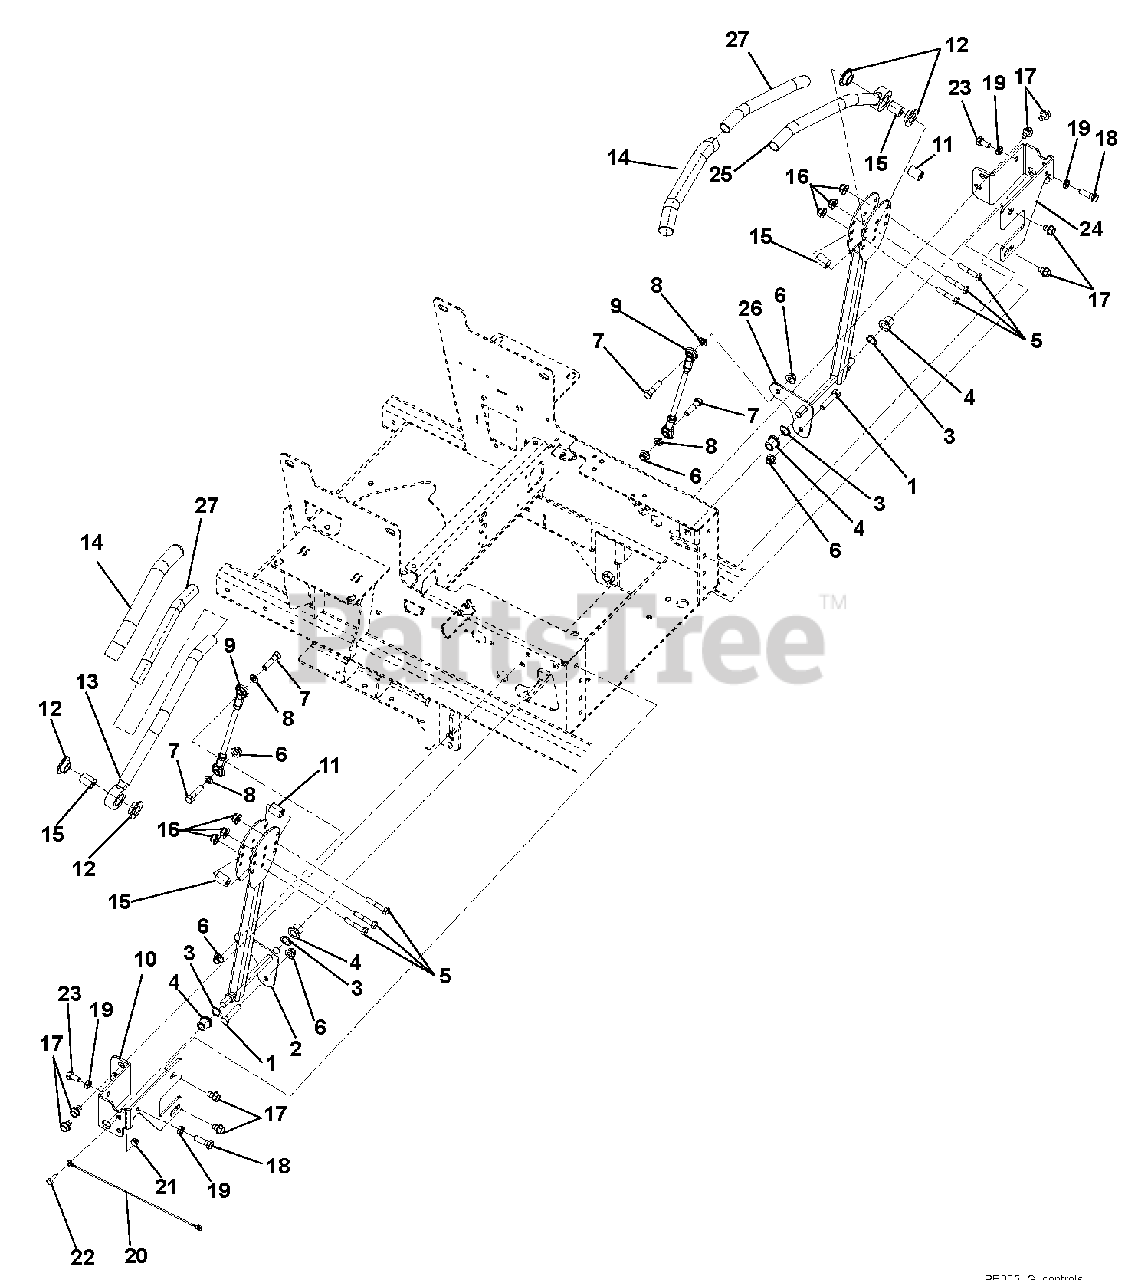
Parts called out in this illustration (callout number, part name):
1	Bolt, Hex .Full Thread 38-16 x 2.00
2	Weldment, Right Hand Control
3	Wave Washer .640 x .875 x .125 Free Height
4	Bushing, Flange Nylon .515 x .750 x .745 x 1.00
5	Bolt, Hex .31-18 x 1.75
6	Nut, .38-16 Nyloc Flange
7	Bolt, Hex .38-16 x 1.50
8	Washer, Locking .38 x .094 Regular
9	Assembly, Steering Linkage
10	Bracket, Right Hand Steering Stop
11	Eccentric
12	Bushing, Flange .762 x 1.48 x .44 Nylon
13	Weldment, Handle Right Hand
14	Grip, Handlebar
15	Spacer, .328 x .76 x 1.01
16	Nut, .31-18 Nyloc Flange
17	Screw, Tapping Hex Washer Head Thread Rolling .38-16 x .50
18	Bolt, Hex .38-16 x 1.25
19	Nut, Hex Jam .375-16
20	Cable, 12.0 Lanyard, Nylon
21	Nut, .25-20 Nyloc Flange
22	Bolt, Hex .25-20 x .75
23	Bolt, Hex .38-16 x .75
24	Bracket, Left Hand Steering Stop
25	Weldment, Handle Left Hand
26	Weldment, Left Hand Control
